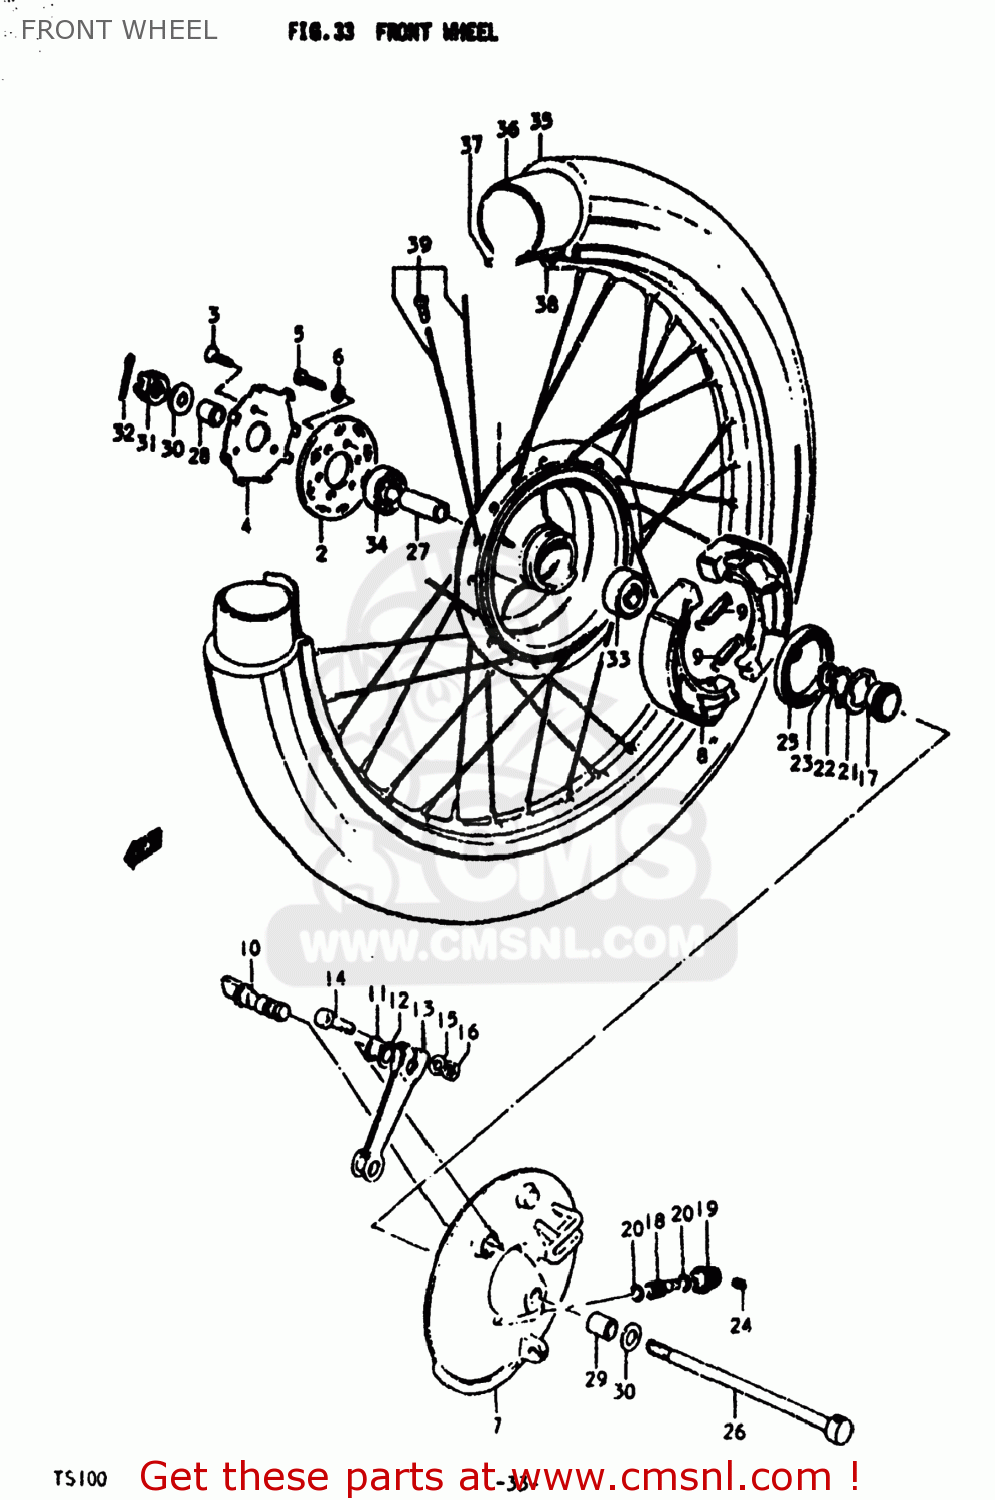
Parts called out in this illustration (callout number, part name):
1	HUB,FR WHEEL
2	FLANGE,FR HUB,R
3	SCREW
4	RETAINER,FR HUB BEARING,R
5	BOLT, UPPER
6	LOCK WASHER
7	PANEL,FRONT HUB
8	SHOE,BRAKE
9	SPRING(L:34)
10	CAM,FRONT BRAKE
11	O-RING (D:2.4 ID:13.8)
12	WASHER (14.5X22X1.6)
13	LEVER,FR BRAKE CAM
14	BOLT(6X33)
15	WASHER
16	NUT
17	GEAR,SPEEDOMETER
18	GEAR,SPEEDOMETER
19	BUSH,METER GEAR OUTER
20	WASHER (5.1X9X0.4)
21	DRIVER,SPEEDOMETER GEAR
22	WASHER(18.5X24X1)
23	CIRCLIP
24	SCREW
25	OIL SEAL (43X58X7)
26	AXLE,REAR
27	SPACER (12.6X19X52)
28	SPACER (12.2X19X18.5)
29	SPACER(12X20X34.5)
30	WASHER
31	NUT 12MM
32	COTTER PIN
33	BEARING
34	BEARING, RH
35	TIRE 2.75-19 070-483MM
36	TUBE 2.75-19 070-483MM
37	PROTECTOR,WHEEL,INNER
38	RIM,FR WHEEL
